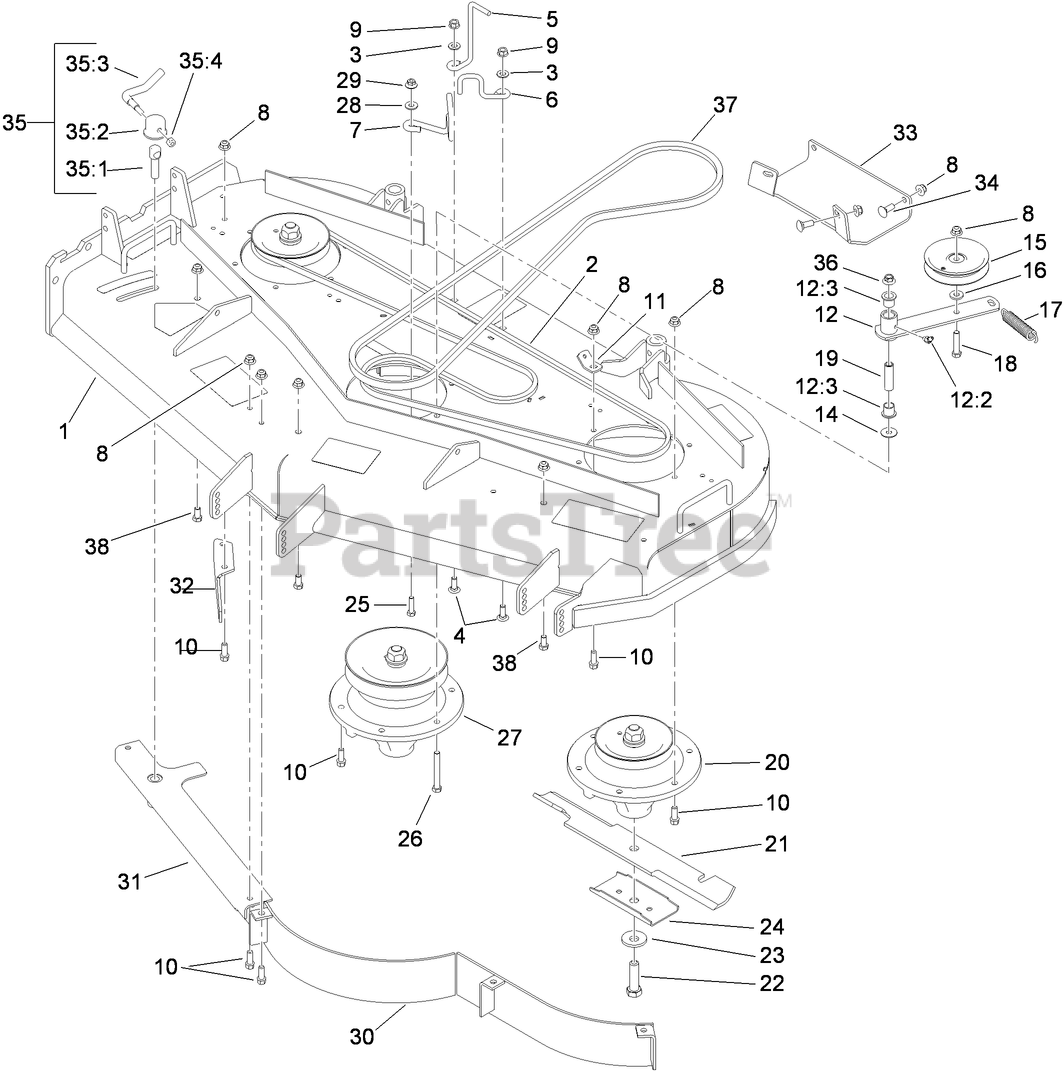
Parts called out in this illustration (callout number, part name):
1	DECK ASM
2	BELT-V
3	WASHER-FLAT
4	SCREW-CARR
5	GUIDE-BELT
6	GUIDE-BELT
7	GUIDE-BELT
8	NUT-HF, NI
9	NUT-HF
10	SCREW-HWH
11	PLATE-SPRING
12	IDLER ARM ASM
12:2	FITTING-LUBE, 45 DEG
12:3	BUSHING-FLANGE
14	WASHER
15	PULLEY-IDLER
16	WASHER-SPACER
17	SPRING-EXTENSION
18	SCREW-HH
19	SPACER
20	SPINDLE ASM
21	BLADE-18IN, HI FLOW
22	SCREW-BLADE
23	Washer-Blade Bolt, Heavy
24	STIFFENER-BLADE
25	SCREW-HH
26	SCREW-HH
27	SPINDLE ASM
28	WASHER-FLAT
29	NUT-HF
31	ADJUSTABLE BAFFLE ASM
32	BAFFLE-DISCHARGE
33	Plate-Skid
34	BOLT-CARR
35	LEVER ASM
35:1	Screw-Lock
35:2	CAP-LOCK
35:3	Lever-Lock
35:4	NUT-LOCK, NI
36	NUT-HF
37	BELT-V
38	SCREW-HH
